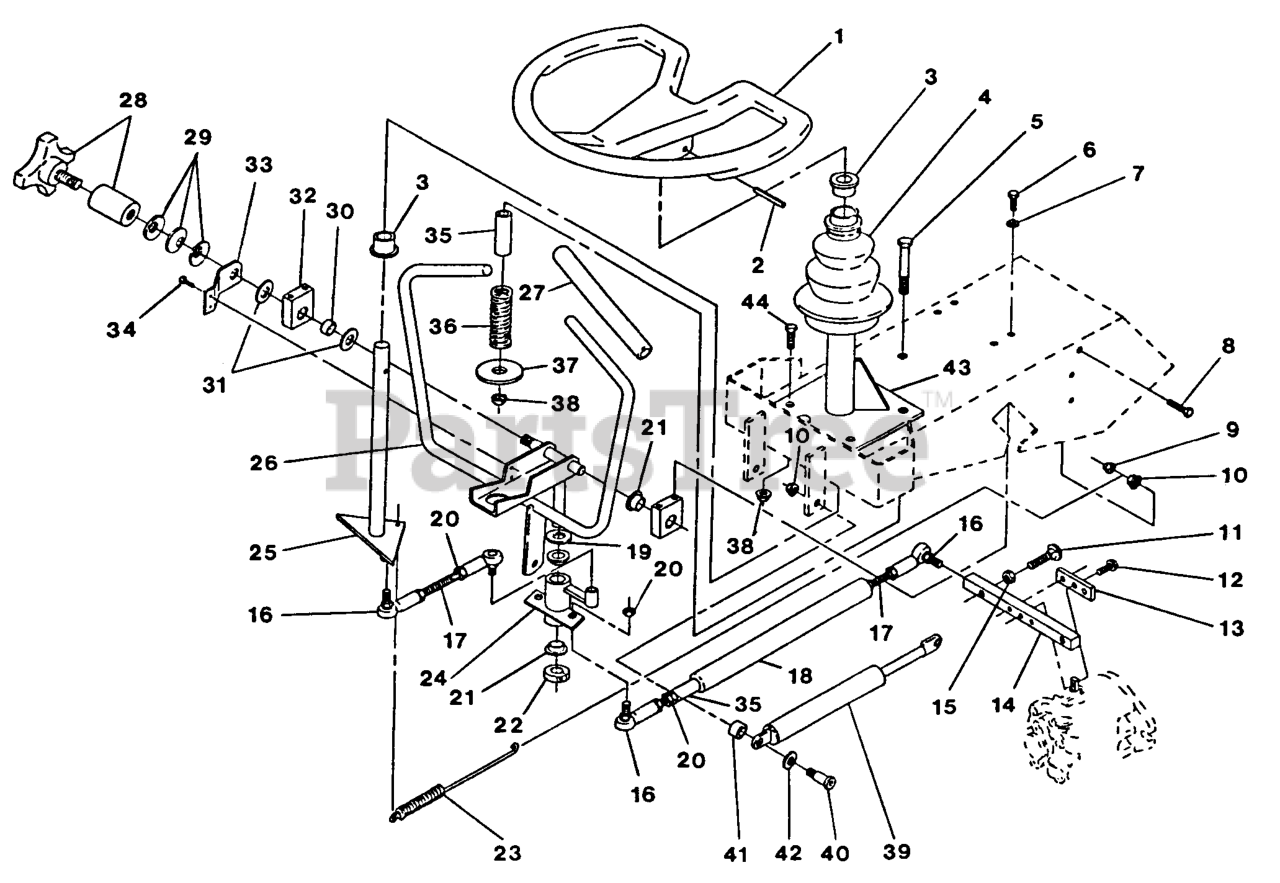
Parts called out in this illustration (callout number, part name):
7	WASHER-LOCK
13	PLATE,CLAMP
14	ARM,PUMP CONTROL
16	BALLJOINT
17	ROD,STEERING
21	BEARING-CONTROL
30	BEARING,CONTROL MOUNT
34	SCREW
35	BUSHING,SPRING GUIDE
36	SPRING-INDICATOR, REVERSE
37	WSHR,REVERSE INDICATOR
41	SPACER-PLATED
